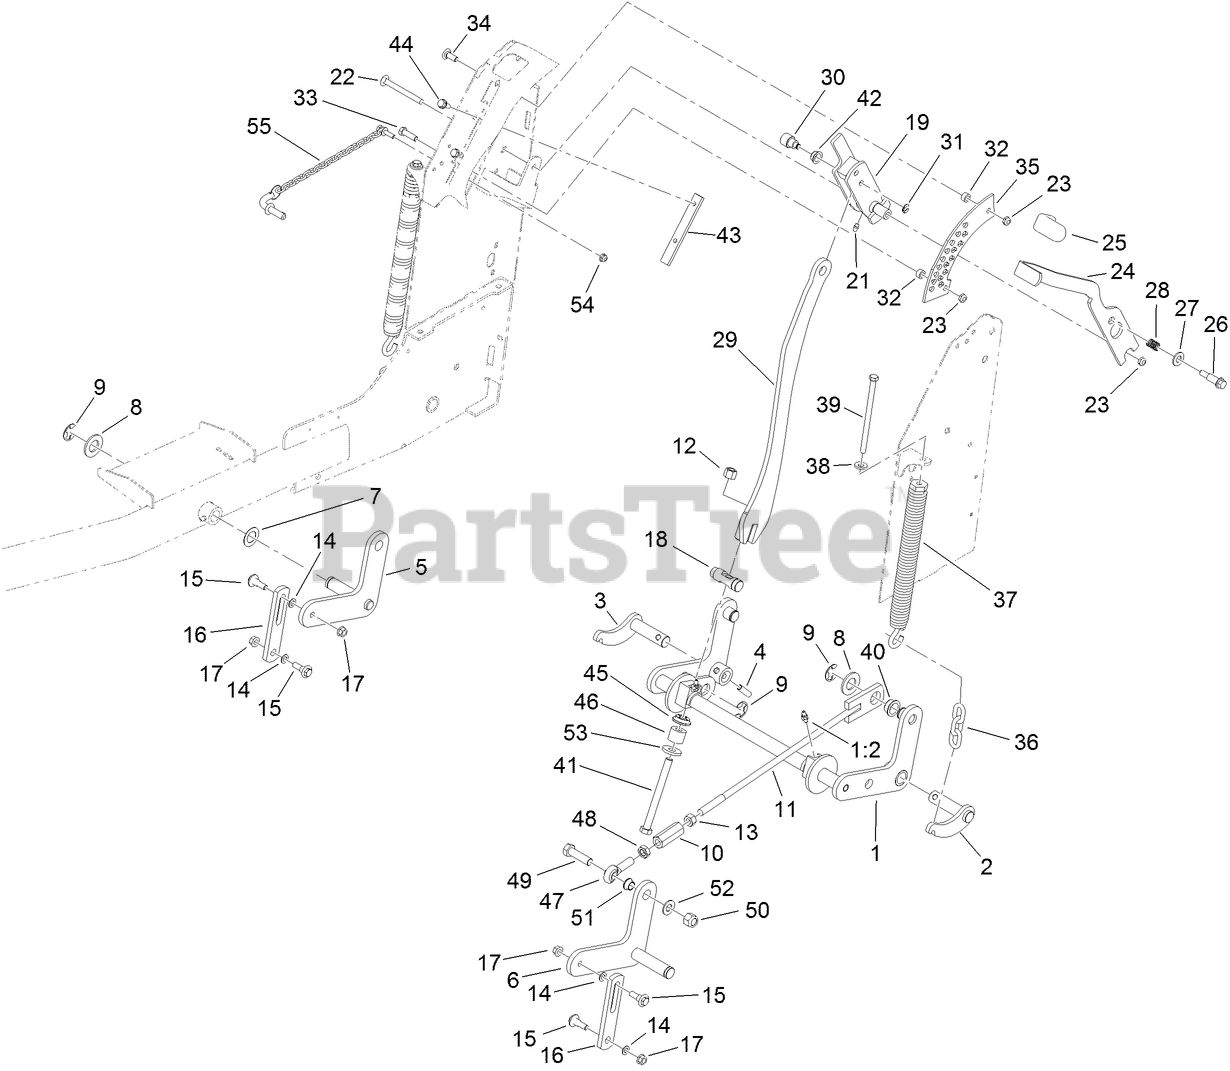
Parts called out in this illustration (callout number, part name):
1	REAR CROSSSHAFT ASM
1:2	FITTING-LUBE, 45 DEG
2	SHAFT-PIVOT, LH
3	SHAFT-PIVOT, RH
4	PIN-SPIRAL
5	RH LIFT ASM
6	LH LIFT ASM
7	WASHER-THRUST
8	WASHER-FLAT
9	RING-RETAINING, EXT
10	LINK-LIFT
11	LIFT ROD ASM
12	NUT-LOCK, NI
13	NUT-HH
14	WASHER
15	SCREW-SHOULDER, HHF
16	LINK-LIFT
17	NUT-HF
18	PIN-HOC
19	HOC HANDLE ASM
21	FITTING-GREASE
22	SCREW-CARR
23	NUT-LOCK, NI
24	LEVER-HOC
25	GRIP-LEVER
26	SCREW-SHOULDER
27	WASHER-FLAT
28	SPRING
29	BAR-LIFT
30	HUB-PIVOT
31	RING-RETAINING
32	SPACER
33	SCREW-HH
34	SCREW-CARR
35	BRACKET-HOC
36	CHAIN-DECKLIFT
37	SPRING-EXTENSION
38	WASHER-BELLEVILLE
39	BOLT-TAP, HH
40	BEARING-FLANGE
41	SCREW-HH
42	BEARING-FLANGE
43	SKID-HANDLE, LIFT
44	SCREW-HWHTF
45	SEAT-SPRING
46	SPRING-URETHANE
47	BALLJOINT-SPHERICAL
48	NUT-JAM
49	SCREW-HH
50	NUT-LOCK, NI
51	BUSHING
52	WASHER-FLAT
53	WASHER
54	NUT-HF
55	HOC PIN ASM
